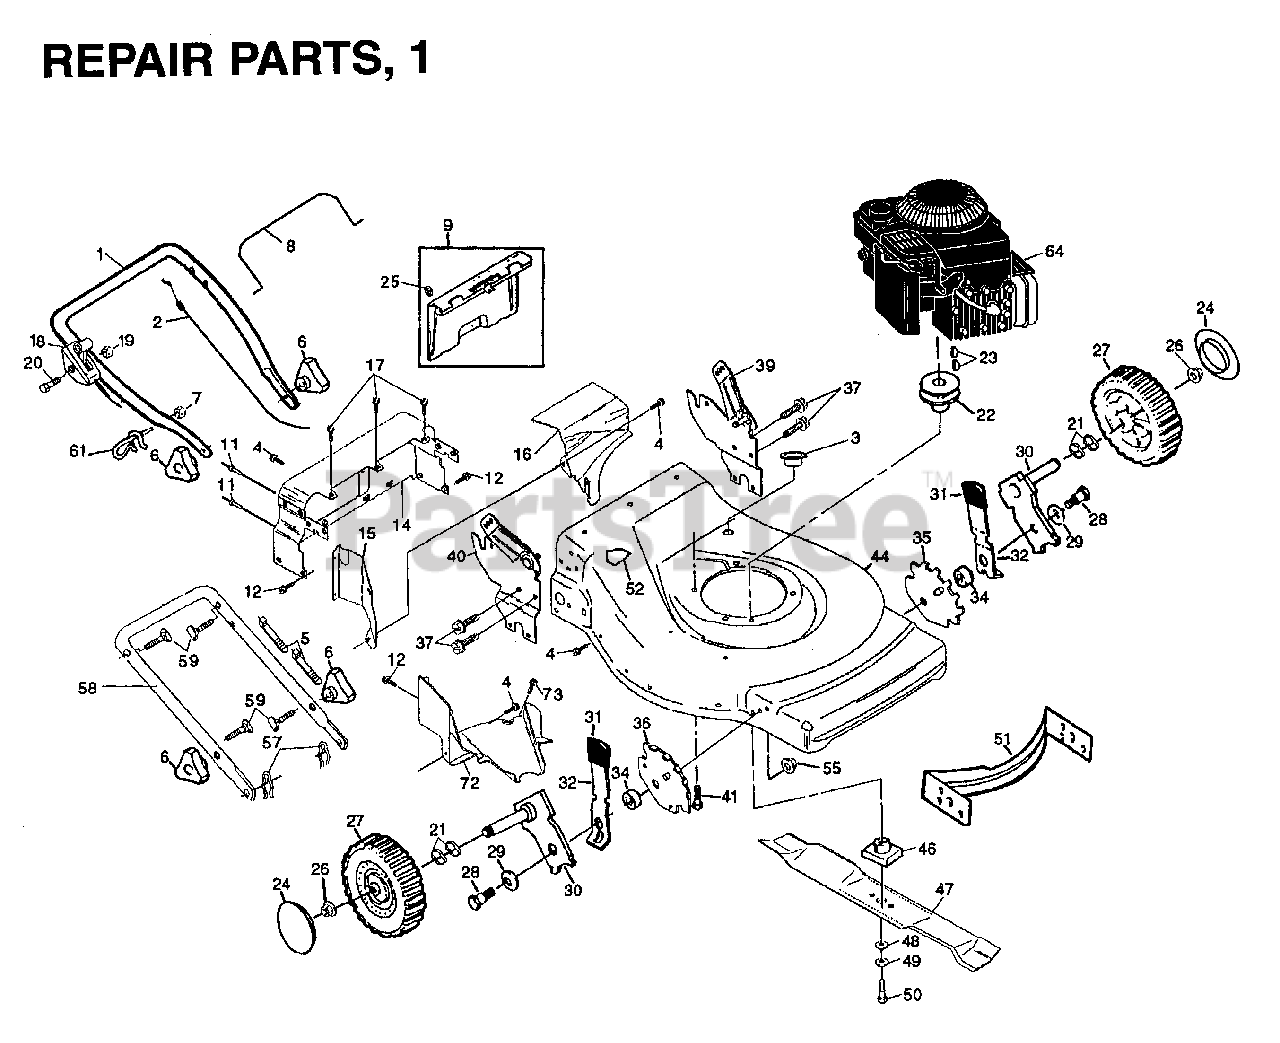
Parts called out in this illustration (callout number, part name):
2	CABLE-ZONE
4	SCREW.HXTAP.10-24
5	CLIP CABLE SNAP
6	HANDLE KNOB
7	NUT.CROWNLOCK.1/4
8	CONTROL BAR
11	RIVET BLIND
15	SIDE BAFFLE
16	DISCHARGE BAFFLE
18	THROTTLE CONTROL
19	NUT.CROWNLOCK.1/4
20	SCREW 1/4-20X1.75
21	WAVE WASHER
22	ENGINE.PULLEY.FWG
23	HI PRO KEY PM
26	HEX FLANGE LOCKNT
27	WHEEL.8X2.PR.LP.RAD.GREY
28	BOLT
29	BELLEVILLE WASHER
30	AXLE ARM
31	SELECTOR KNOB
32	SELECTOR SPRING
34	RP SPACER HT ADJ
37	SCREW
46	RP BLADE ADAPTOR
47	%BLADE, MULCH
48	WASHER,HARDEN
49	LOCKWASHER
50	SCREW, HEX HD 3/8-24 X 1-3/8
52	DECAL MOWER CUT/FINGER
55	LOCKNUT
57	HAIRPIN COTTER
59	HANDLE BOLT
61	ROPE GUIDE
72	BAFFLE BELT COVER
73	SCREW.HX.13X.750
